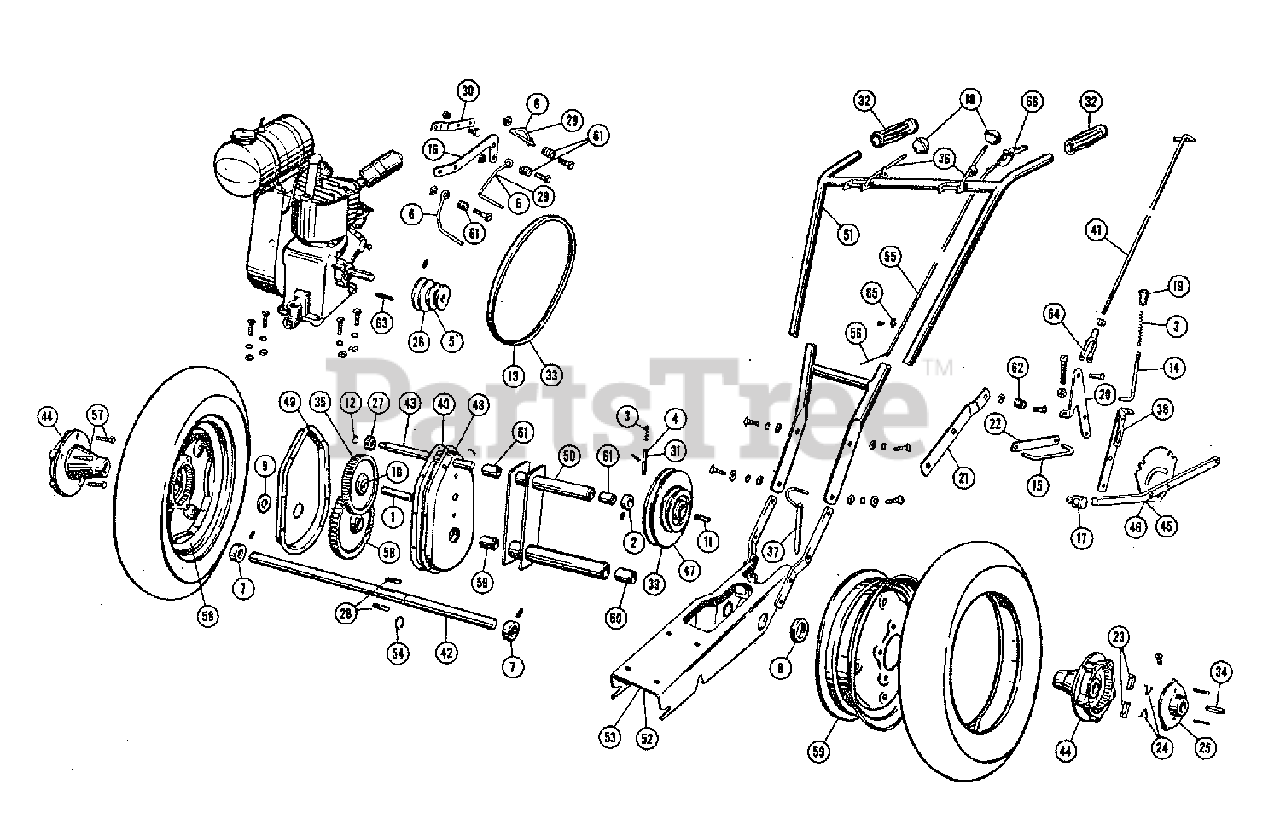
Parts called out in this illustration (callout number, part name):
1	SPINDLE, Intermediate
2	COLLAR, Set (Pulley Shaft)
3	SPRING, Transmission Sheave
4	PIN, Transmission Sheave, 1-1/2 HP
5	PULLEY, Engine, 1-1/2 HP
6	STOP, Belt
7	COLLAR, Set (Axle)
8	COLLAR, Set (Axle Housing)
10	BUSHING, Intermediate
11	KEY, Transmission Sheave
12	RING, Retaining
13	BELT, Transmission, 1-1/2 HP
15	LINK, Throw-Out
16	HOLDER, Belt Stop
17	SLIDE, Throw-Out
18	BALL, Clutch Lever
19	KNOB, Plunger
20	CLUTCH LEVER, Lower
21	FRAME, Extension
22	STRAP, Throw-Out
23	RATCHET DOG, Right or Left
24	SPRING, Ratchet
25	RATCHET CAGE, Right or Left
26	ENGINE PULLEY, 3hp
27	PINION, Reduction
28	KEY, Axle
29	BELT STOP, 3HP
30	BRACKET, Belt Holder, 3HP
31	PIN, Transmission Sheave, 3HP
32	GRIP, Rubber
33	BELT, Transmission, 39", 3HP
34	KEY, Ratchet Cage
35	GEAR ASSEMBLY, Cluster
36	LEVER ASSEMBLY, Clutch
37	PIN ASSEMBLY, Draw Bar
38	LEVER ASSEMBLY, Shift
39	TRANSMISSION SHEAVE, 1-1/2 HP
40	GASKET, Gear Case
41	ROD, Clutch
43	SHAFT, Pulley
44	HUB, Wheel
45	THROW-OUT ASSEMBLY
46	THROW-OUT ASSEMBLY
47	TRANSMISSION PULLEY ASSEMBLY
48	GEAR CASE
49	COVER, Gear Case
50	HOUSING ASSEMBLY, Bearing
51	HANDLE ASSEMBLY
52	FRAME ASSEMBLY, 1-1/2 HP
53	FRAME ASSEMBLY, 3 HP
54	RING, Retaining
55	WIRE HOUSING, Throttle
56	WIRE, Throttle Control
57	BOLTS, Hub
58	DRIVE GEAR
60	BUSHING, Axle
61	BUSHING, Pulley Shaft
63	KEY, Engine Pulley
64	END ASSEMBLY, Rod
65	CLAMP, Cable
66	LEVER ASSEMBLY, Throttle
